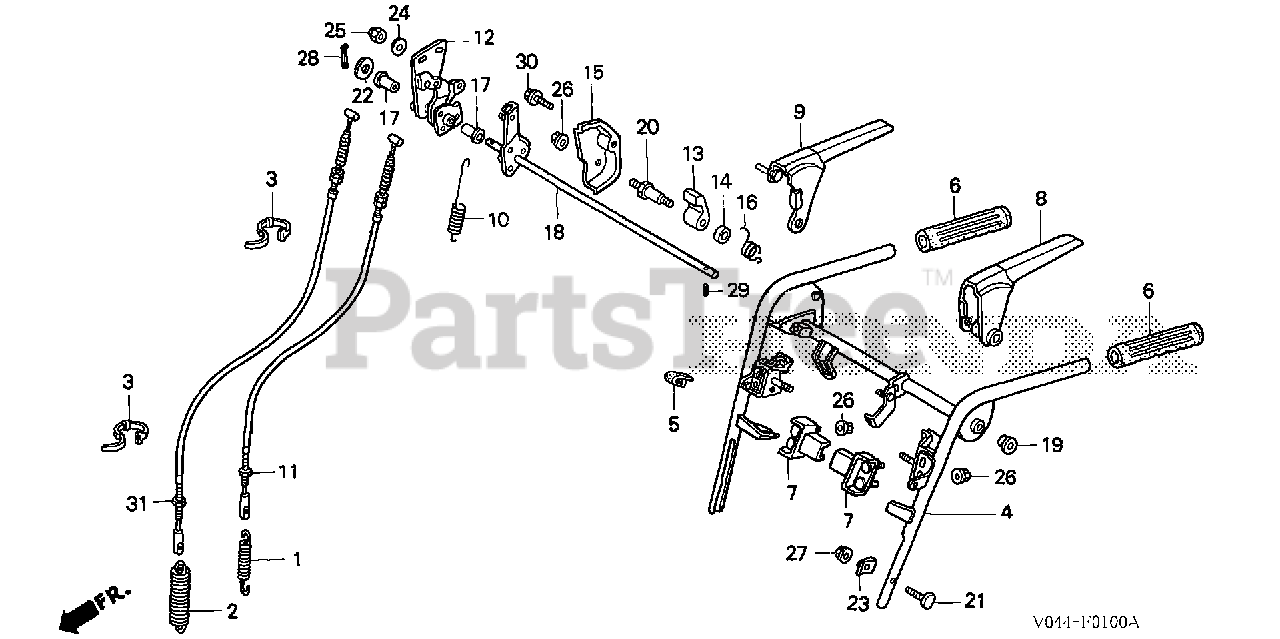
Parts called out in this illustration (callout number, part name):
1	SPRING, TENSIONER ROLLER
2	SPRING, TENSIONER ROLLER (AUGER)
3	BAND, WIRE (95MM)
4	PIPE, HANDLE (UPPER)
5	RUBBER, STOPPER
6	GRIP, HANDLE
7	STOPPER, CHANGE LEVER
8	LEVER, CLUTCH
9	LEVER, AUGER CLUTCH
10	SPRING, CLUTCH LEVER
11	CABLE, CLUTCH
12	BOSS, CAM LOCK
13	RATCHET, LEVER
14	COLLAR, RATCHET
15	COVER, RATCHET
16	SPRING, RATCHET
17	BUSH (13X22.5) (GRAY)
18	SHAFT, CLUTCH LEVER
19	BUSH (14MM)
20	BOLT, PIVOT (6MM)
21	BOLT, HANDLE HOLDER
22	WASHER, THRUST (10MM)
23	WASHER, FRAME JOINT
24	WASHER (6MM)
25	NUT, CAP (6MM)
26	NUT, FLANGE (6MM)
27	NUT, FLANGE (8MM)
28	PIN, COTTER (3.0X18)
29	PIN, SPRING (4X16)
30	BOLT, FLANGE (6X10)
31	CABLE, CLUTCH
